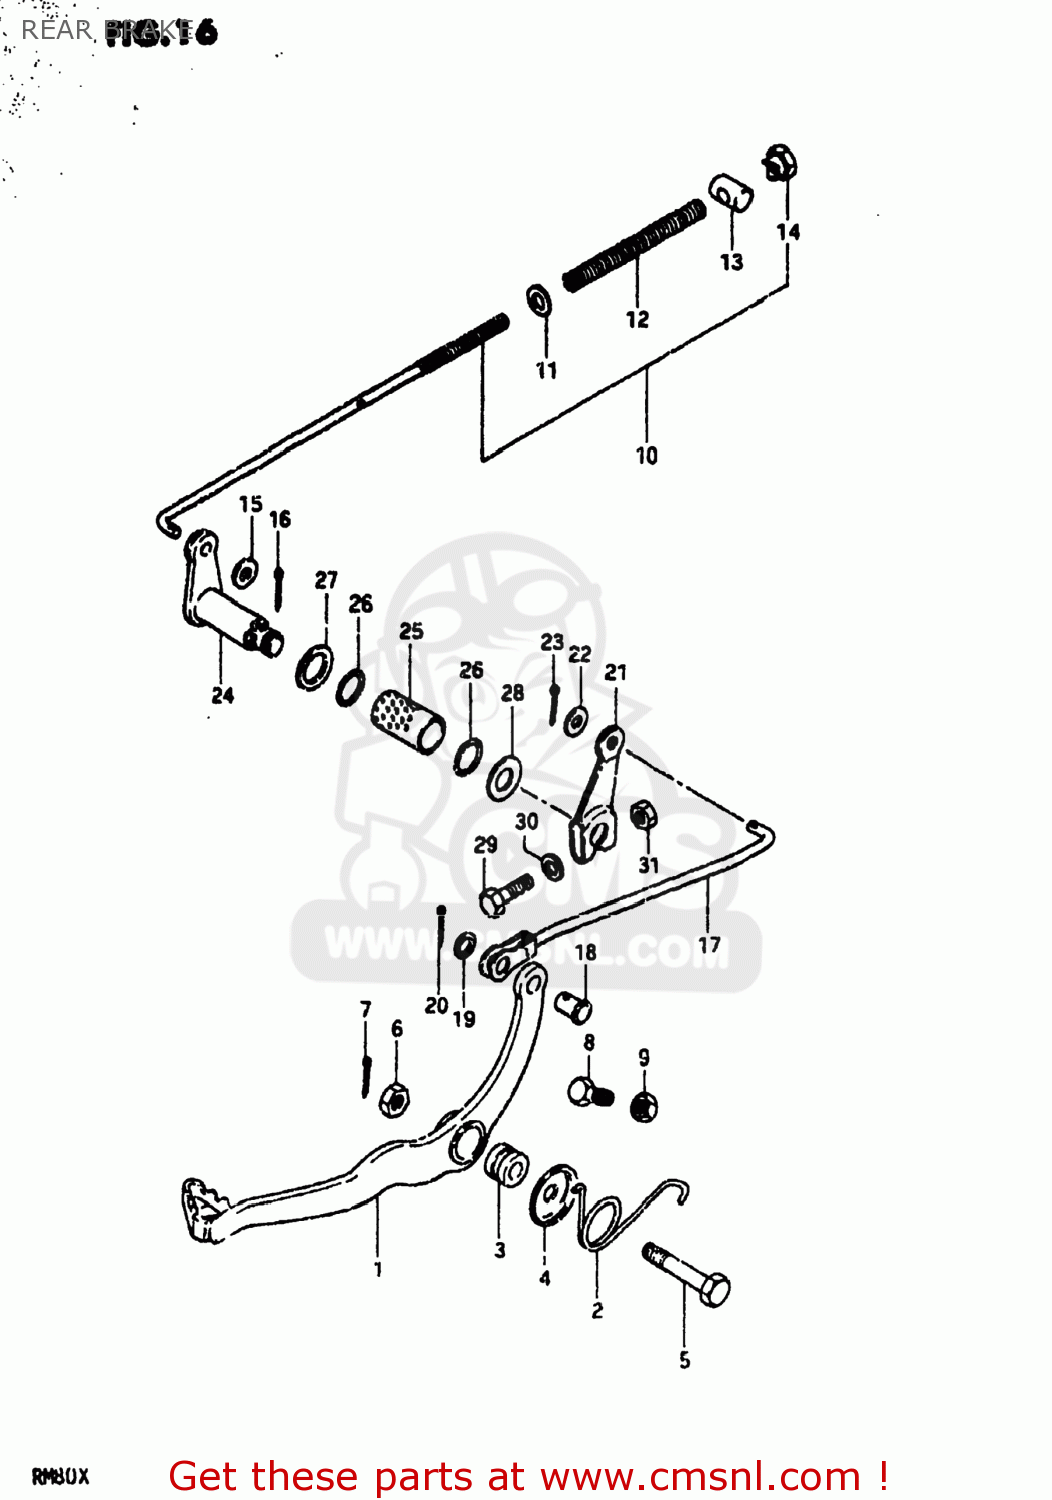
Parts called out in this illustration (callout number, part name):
1	PEDAL,BRAKE
2	SPRING
3	SPACER,BRAKE PEDAL
4	WASHER,BRAKE PEDAL
5	BOLT 8X50
6	NUT 8MM
7	PIN 20X20
8	BOLT(6X23)
9	NUT
10	ROD ASSY,RR BRAKE RR
11	WASHER
12	SPRING
13	PIN(11X18)
14	NUT
15	WASHER
16	PIN 20X20
17	ROD, REAR BRAKE FRONT
18	PIN
19	WASHER
20	PIN 20X20
21	ARM,REAR BRAKE ROD,OUTER
22	WASHER
23	PIN 20X20
24	ARM, REAR BRAKE INNER
25	BUSHING,REAR BRAKE ROD ARM
26	O RING(D:1.7,ID:15.5)
27	WASHER
28	WASHER
29	BOLT
30	WASHER
31	NUT
